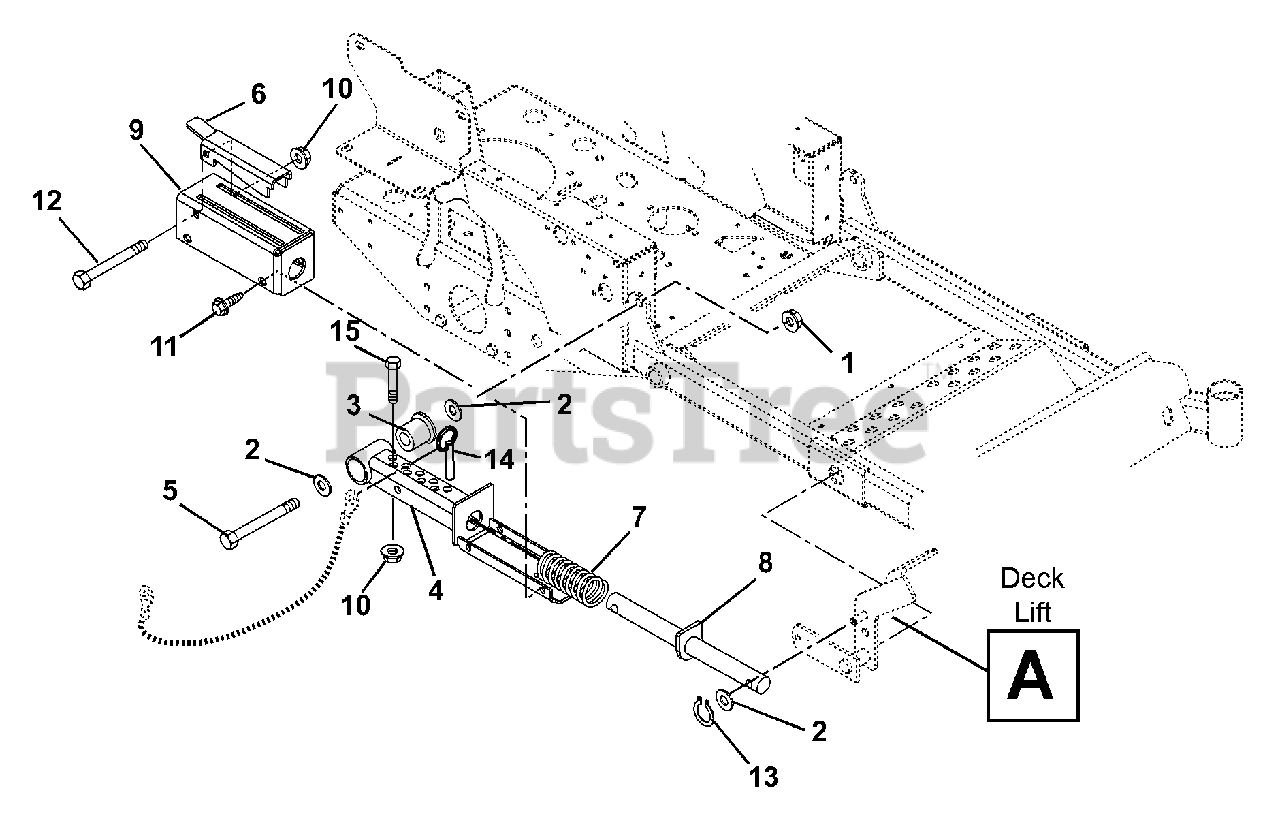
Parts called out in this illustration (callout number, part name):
1	@NUT-LK-NYL-FLG .50-13 YWZC
2	WSHR-FL-STL .531X1.250X.10 YWZ
3	BEARING, PEDESTAL
4	WMT, MECHANICAL LIFT
5	@BLT-HEX .50-13X3.75 GR5 YWZC
6	LOCK-UP, MECH LIFT
7	SPR-COMP 1.13X1.48X5.10 WD 165
8	WMT, MECH LIFT SHAFT (.50)
9	WMT, MECH LIFT COVER
10	@NUT-LK-NYL-FLG .38-16 YWZC
11	@SCR-TAP .38-16X.50 HWH TR YWZ
12	@BLT-HEX .38-16X3.25 GR5 YWZC
13	RG-RTNG-EXT .500X.050 (SNAP)
14	PIN, SPRING BALL .375OD X 1.50
15	@BLT-HEX .38-16X2.00 GR5 YWZC
